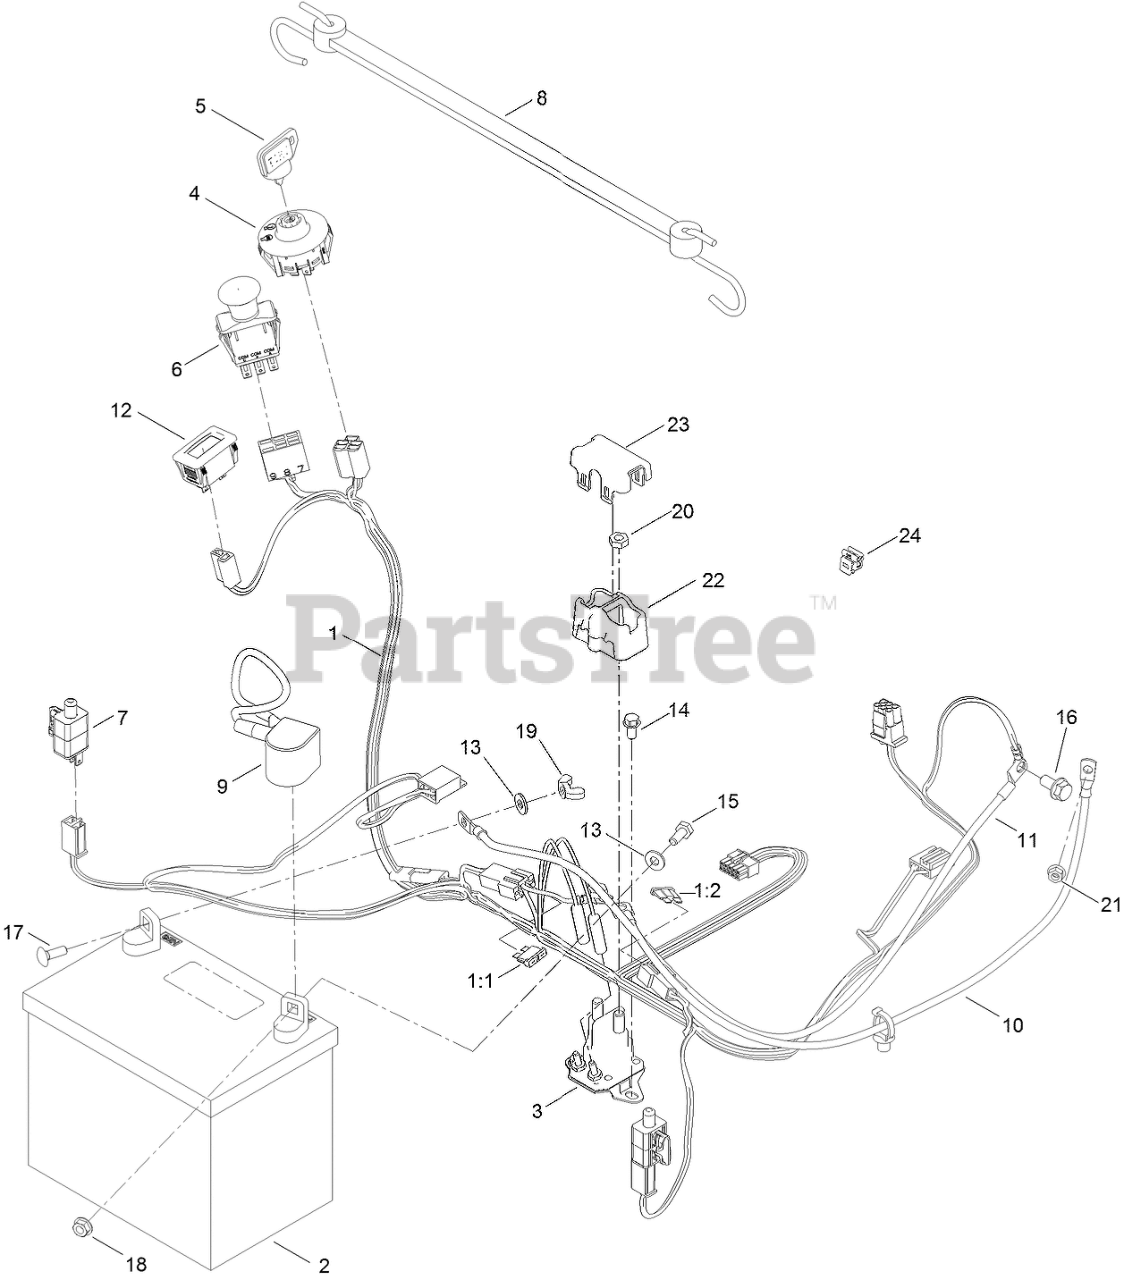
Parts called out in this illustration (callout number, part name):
1	HARNESS-WIRE
1:1	FUSE-BLADE, 15 AMP
1:2	FUSE-BLADE, 25 AMP
2	BATTERY
3	SOLENOID
4	SWITCH-IGNITION
5	KEY-IGNITION
6	SWITCH-PTO
7	SWITCH
8	STRAP-RUBBER
9	CABLE-BATTERY, POS
10	CABLE-BATTERY, RED (8 GAUGE)
11	CABLE-BATTERY, BLACK
12	HOURMETER
13	WASHER-FLAT
14	SCREW-HWH
15	SCREW-HH
16	SCREW-HHF
17	BOLT-CARR
18	NUT-HF
19	NUT-WING
20	NUT-JAM
21	NUT-HF
22	COVER-SOLENOID
23	CAP-SOLENOID
24	CLIP-HARNESS
